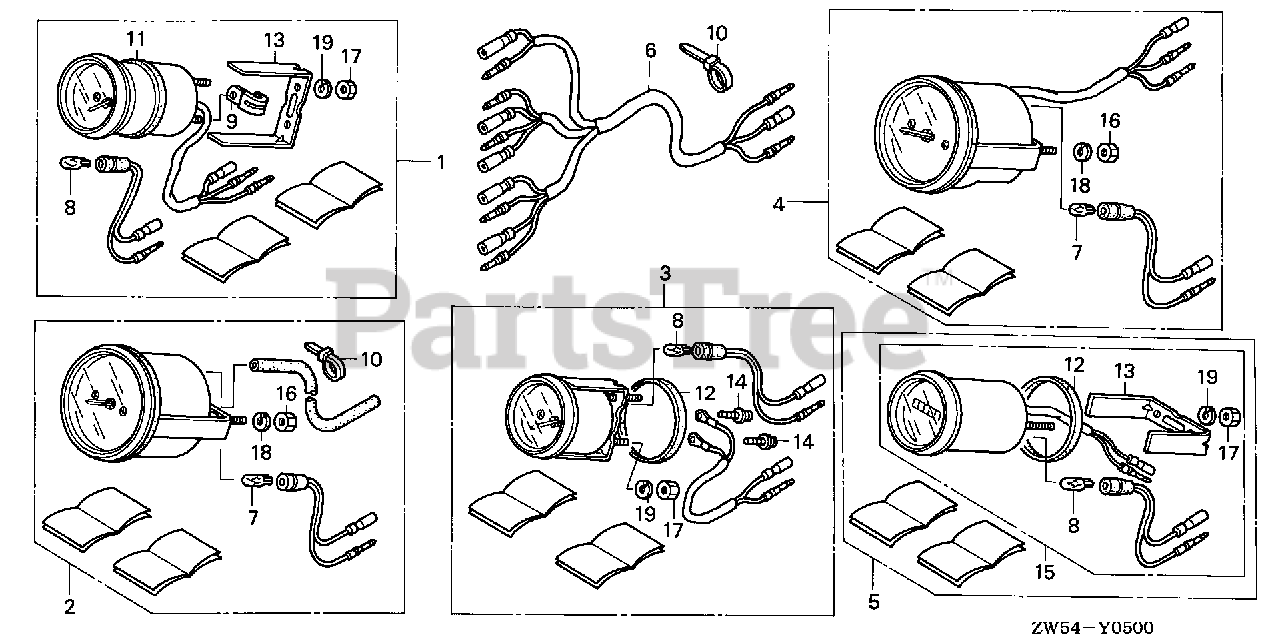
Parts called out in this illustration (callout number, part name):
1	METER KIT, TRIM
1	METER KIT, TRIM (B)
2	SPEEDOMETER KIT
2	SPEEDOMETER KIT *NHA85* (B)
3	METER KIT, VOLT
3	METER KIT, VOLT *NHA85* (B)
4	METER KIT, TACHO
4	METER KIT, TACHO (B)
5	METER KIT, HOUR
5	METER KIT, HOUR *NHA85* (B)
6	HARNESS ASSY., METER (B)
7	BULB, WEDGE BASE (T10)
8	BULB, WEDGE BASE (12V 1.7W)
10	BAND, SELF-LOCK
14	SCREW-WASHER (3X22)
15	METER ASSY., HOUR
15	METER ASSY., HOUR (B)
16	NUT, HEX. (5MM)
17	NUT, HEX. (4MM)
18	WASHER, SPRING (5MM)
19	WASHER, SPRING (4MM)
